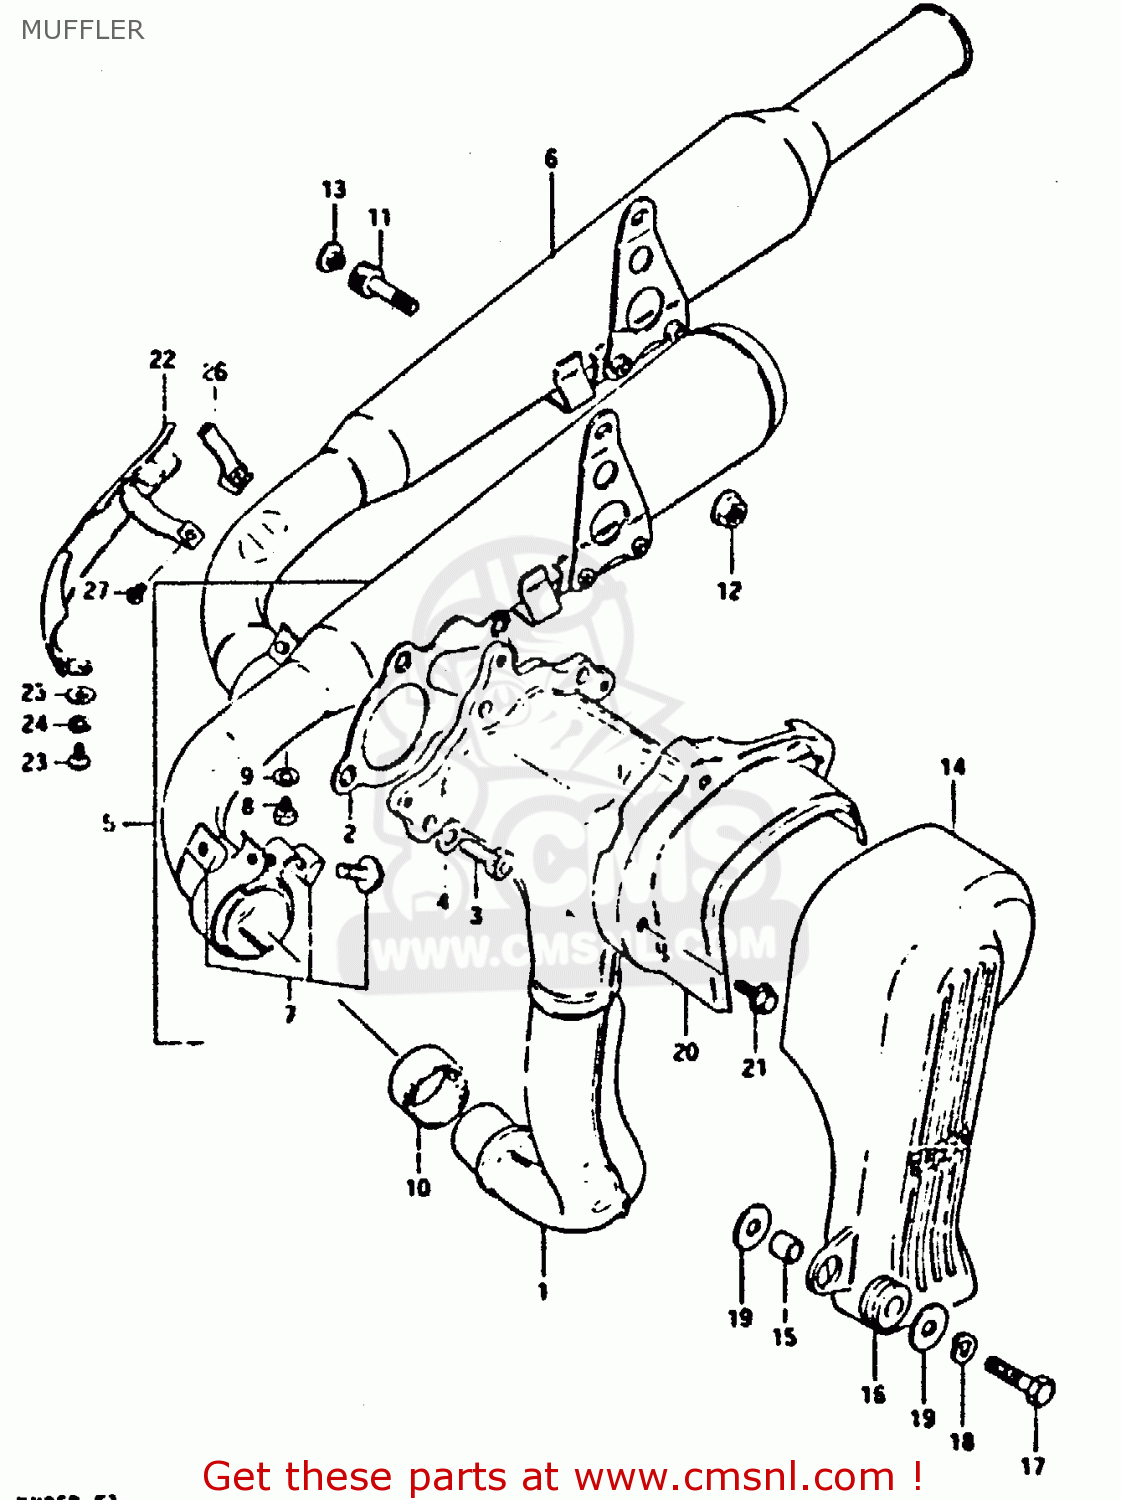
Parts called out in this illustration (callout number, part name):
1	PIPE,MUFFLER
2	GASKET,TURBO OUT
3	BOLT(8X20)
4	WASHER
5	MUFFLER ASSEMBLY
6	MUFFLER ASSY
7	PLATE SET,MUFFLER
8	BOLT
9	WASHER
10	CONNECTOR,MUFFLER
11	BOLT
12	NUT
13	CAP
14	COVER,MUFFLER NO.1
15	SPACER (8.8X12X11)
16	CUSHION
17	BOLT
18	LOCK WASHER
19	WASHER (8.5X20X1.6)
20	COVER, INNER
21	BOLT
22	COVER,MUFFLER
23	SCREW
24	LOCK WASHER
25	WASHER
26	CLAMP,MUFFLER COVER
27	SCREW
